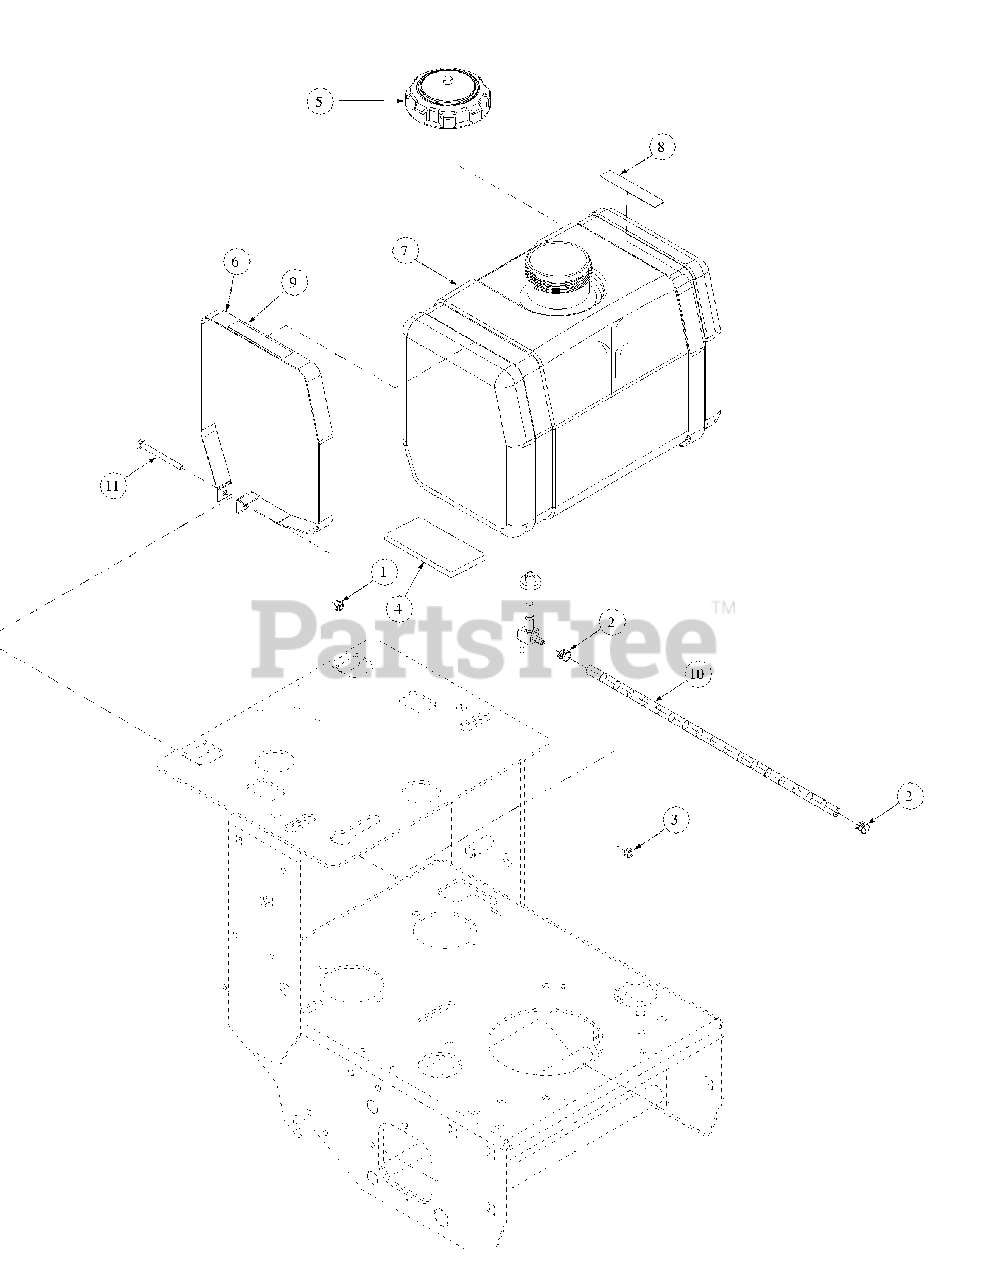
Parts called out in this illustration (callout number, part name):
1	Lock Nut, Nylon Insert, 1/4-20 Grade A
2	Uni-Clamp, #5077-136
3	Nut, 1/4-20, Grade A
4	Stop Pad, Rubber
5	Fuel Cap, 3.5
6	Fuel Tank Strap
7	Fuel Tank
8	Mower Warning Label, Turn Off Engine
9	Mower Instruction Label, Fuel Valve
10	18" Fuel Hose
11	Carriage Bolt, 1/4-20 x 3.00 Grade 5
12	Grommet Fuel Tank
13	Shut Off Fuel Tank
